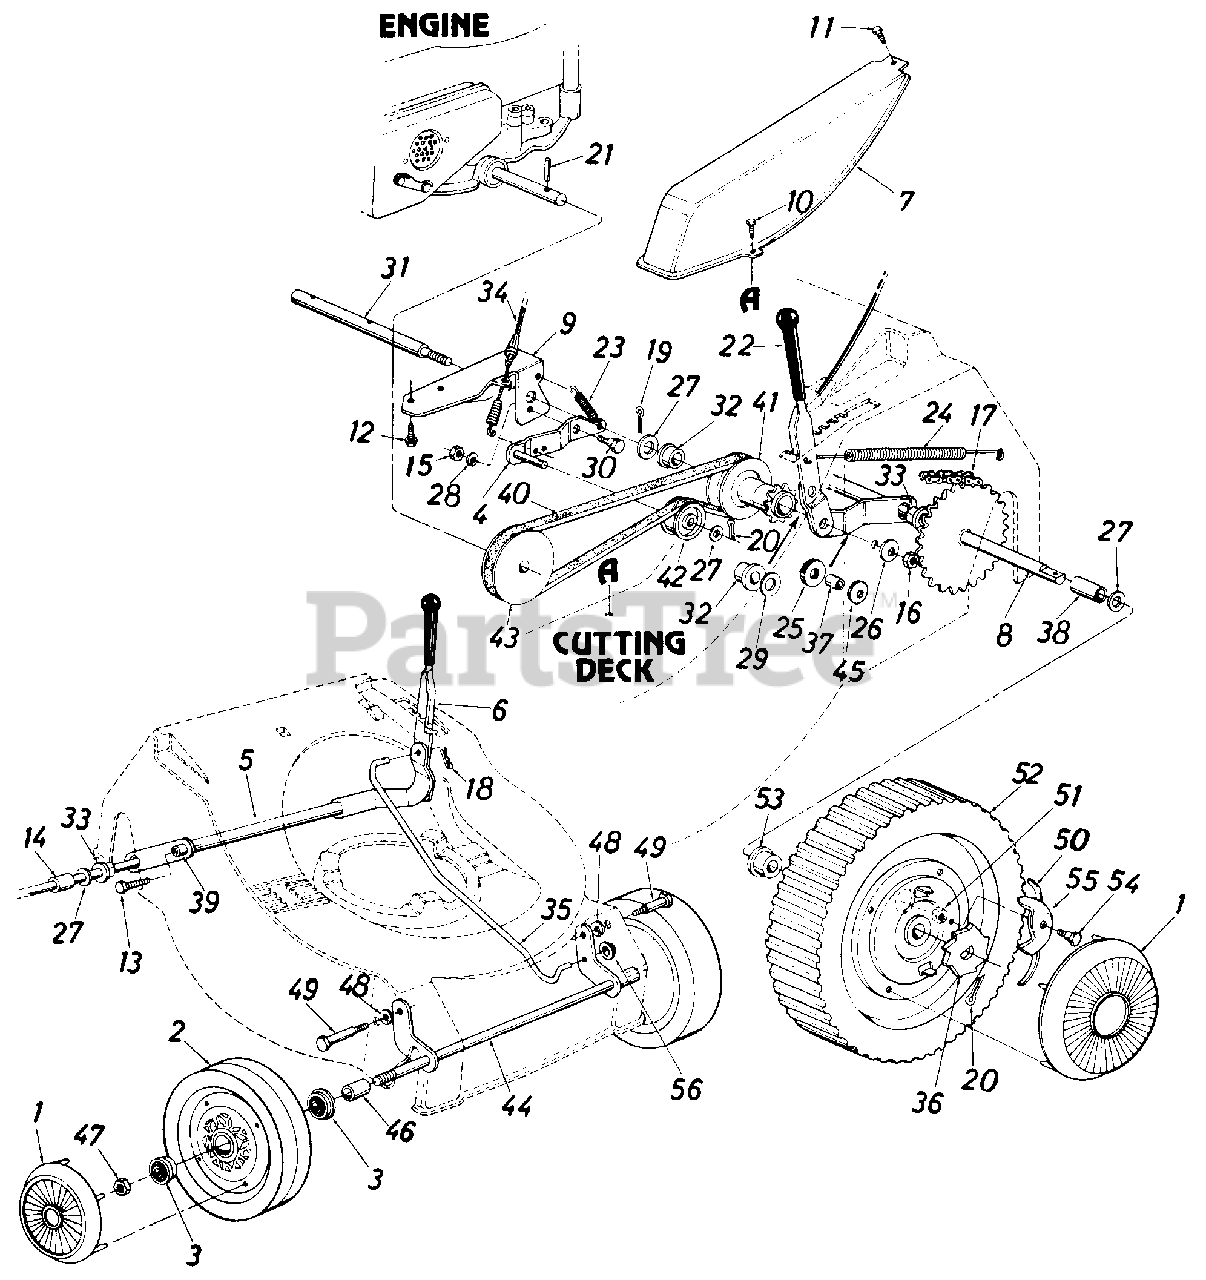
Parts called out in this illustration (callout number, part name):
1	Hub Cap
2	Wheel Ass'y. Comp. 8 x 1.75-Front
3	Flanged Ball Brg. .500" I.D.
4	Idler Brk't. Ass'y.
5	Axle Ass'y.
6	Height Adj. Handle
7	Belt Cover
8	Rear Shaft Ass'y.
9	Bracket-Pulley Shaft
10	Hex B-Tap Scr. 1/4 x .38" Lg.
11	Hex Drilling Scr. #10 x .50"
12	Hex Wash. Hd. B-Tap Scr. 5/16-18 x .50" Lg.
13	Hex Wash. Hd. TT-Tap Scr. 3/8-16 x 1.00" Lg.
14	Spacer. 526" I.D. x .690" O.D. x .640" Lg.
15	Hex Nut 1/4-20 Thd.*
16	Hex Jam Nut 3/8-16 Thd.
17	#48 Chain 1/2" Pitch x 34 Links-E.
18	Intern. Cot. Pin 5/16" Dia.
19	Cotter Pin 3132" Dia. x 1.00" Lg.*
20	Cot Pin 118" Dia. x 1.00" Lg.
21	Spring Pin Spir. 3/16" Dia. x 1.50" Lg.
22	Grip-Black
23	Extension Spring .33" O.D. x 1.12" Lg.
24	Extension Spring .50" O.D. x 4.25" Lg.
25	Rubber Wash.
26	Bell-Wash. .400" I.D. x .88" O.D.
27	Fl-Wash. .531" I .D. x .930 "O.D.
28	L-Wash. 1/4" I.D.
29	Fl-Wash. 390" I.D. x 1.00" O.D.
30	Shld. Bolt .375" Dia. x .181
31	Pulley Shaft .500" Dia.
32	Flange Brg. .506" I.D. Plastic
33	Hex Flange Brg. x .506" I.D. Plastic
34	Drive Clutch Cable-50" Lg.
35	Linkage Rod .38" Dia.
36	Ratchet Wheel
37	Spacer.395" I.D. x .503" O.D. x .562" Lg.
38	Spacer.75" I.D. x .88" O.D. x 1.41" Lg.
39	Spacer.385" I.D. x .503" O.D. x.270" Lg.
40	"V"-Belt 1/2" x 33" Lg.
41	Pulley w/9 Tooth Sprocket Ass'y.
42	Flat Idler Plastic 1.62" Dia.
43	"V"-Pulley .50" I.D. x 2.52" O.D.
44	Front Axle Ass'y.
45	Belleville Washer .40" I.D. x 1.13" O.D.
46	Sleeve .526" I.D. x .690" O.D. x .880 Lg.
47	Hex Ins. L-Nut 1/2-20 Thd.
48	Int. L-Wash. 3/8" I.D.
49	Shld. Bolt .625 Dia. x .425
50	Spring-Nylon
51	Hex Ins. L-Nut 1/4-20 Thd.
52	Wheel Ass'y. Comp. 9.25 x 1.75 Rear
53	Flanged Ball Brg. .500" I.D.
54	Shoulder Bolt .342" Dia. x .268
55	Pawl
56	Cap Speed Nut 5/16" Rod
